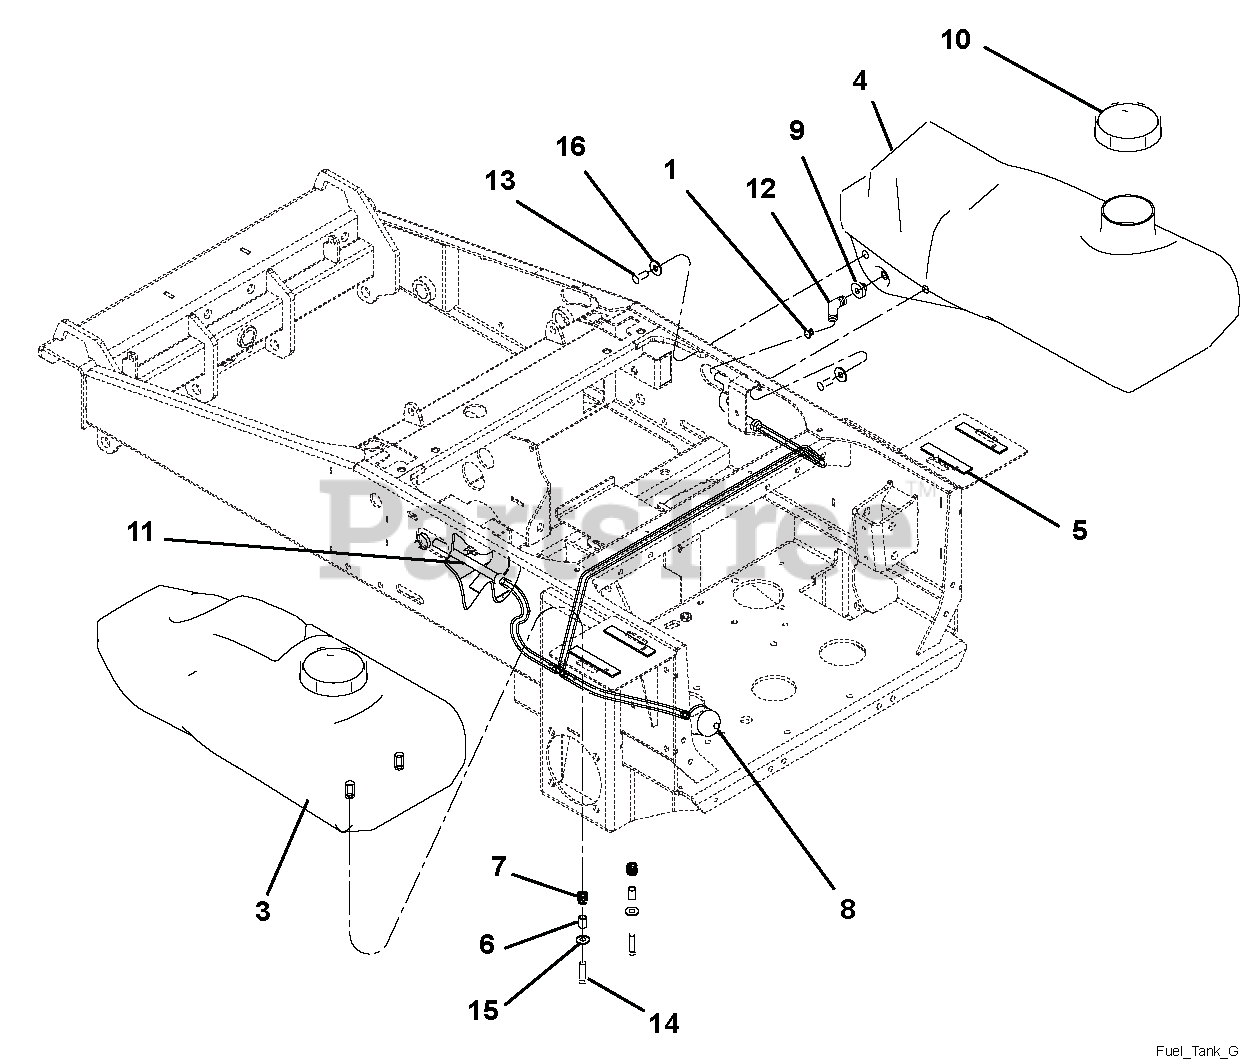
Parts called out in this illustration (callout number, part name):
1	CLAMP, HOSE - 1/2" SPRING
3	TANK, LH MIDMOUNT BLANK W/CAP
4	TANK, RH MIDMOUNT BLANK W/CAP
5	FOAM, .125 X .750 X 4.00
6	SPACER, GAS TANK ATTACHMENT
7	SPRING, COM .660 X .067 X .625
8	FUEL FILTER - KAWASAKI
9	GROMMET, RUBBER TANK S/O
10	CAP, FUEL S/O
11	ASSY, FUEL LINE W/CHECKVALVES
12	FTG, 90 1/4HOSE X 1/2HOSE S/O
13	BOLT, 3/8-16X.750 HEX 5 Y
14	@BLT-HEX .38-16X1.25 GR5 YWZC
15	@WSHR-FL-STL.38X.875X.083 YWZC
16	WASHER, .375 REG FLAT Y
